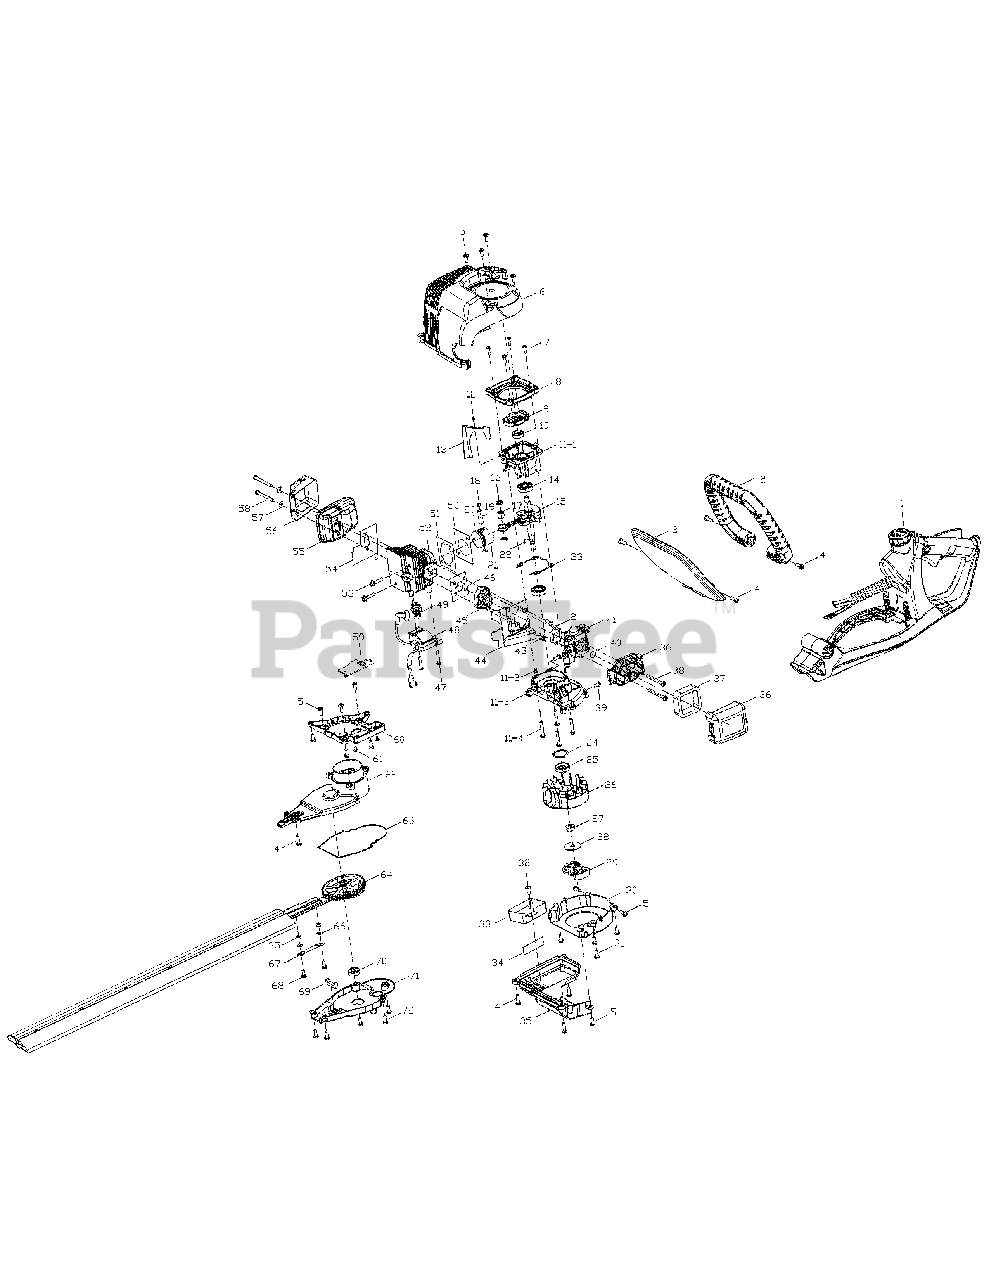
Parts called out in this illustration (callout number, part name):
1	Housing Assembly
6	Starter Housing Assembly
8	Connect Case
9	Pawls Assembly
11	Crank Case Assembly
13	Baffle Cylinder
14	Ball Bearing
15	Crank Assembly
16	Spacer, Piston
17	Needle Bearing
20	Piston Ring
22	Key (Flywheel)
23	Crank Case Gasket
24	C-Clip
27	Spacer, Piston
29	Clutch Assembly
30	Crank Case Cover
35	Engine Cover
36	Air Cleaner Assembly
37	Filter, Air
40	O-Ring (Air)
41	Carburetor
42	Gasket (Carburetor)
45	Insulator
46	Gasket (Insulator)
48	Ignition Assembly
50	Gasket Cylinder
51	Gasket Cylinder
54	Gasket Muffler
55	Muffler Assembly
62	Brake Assembly
64	Gear Assembly
65	Spacer, Piston
67	Steel Board
